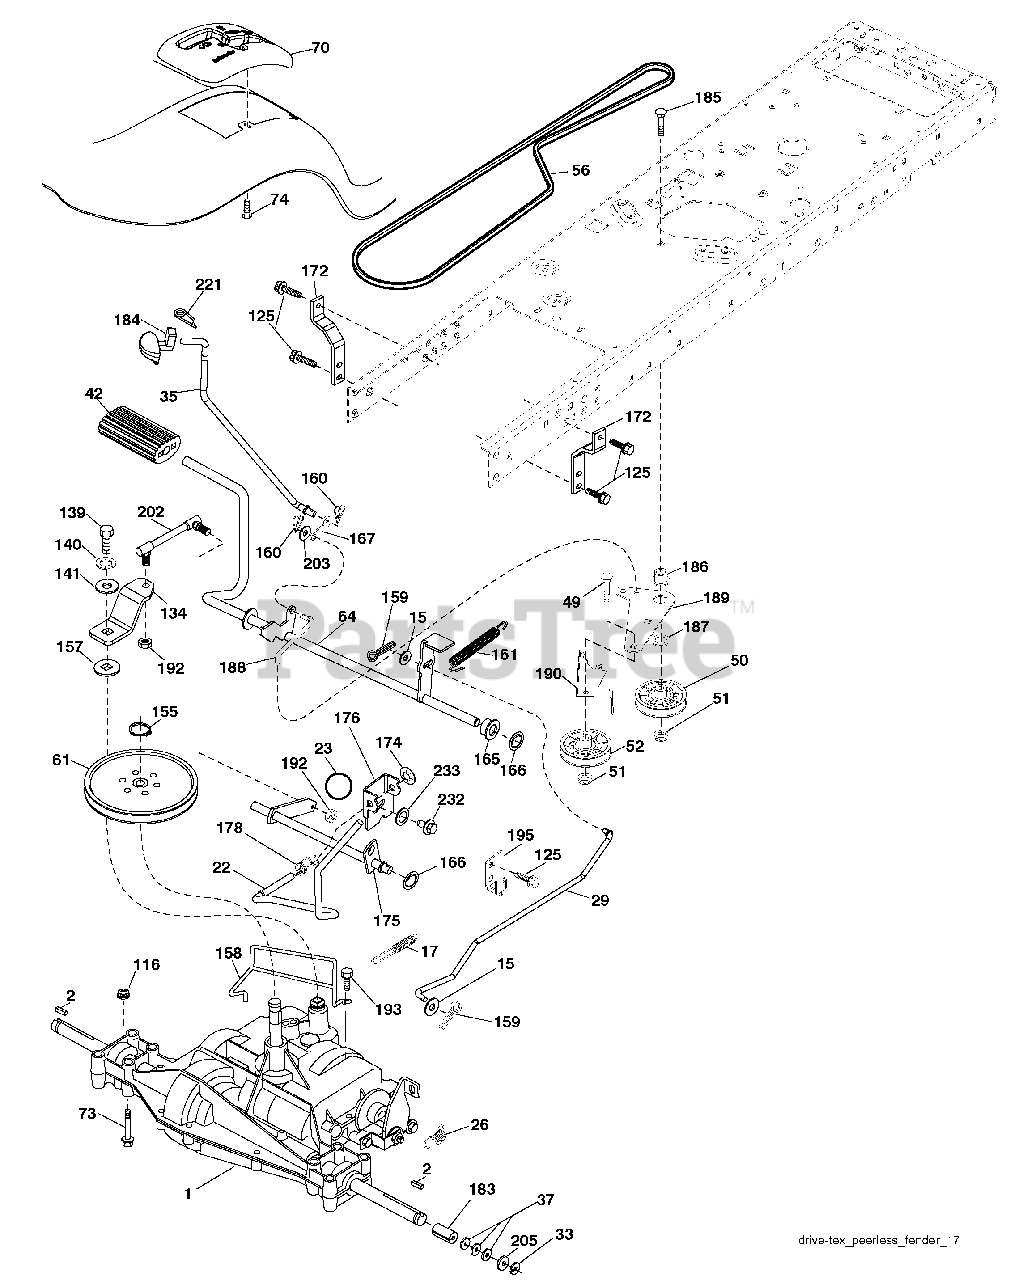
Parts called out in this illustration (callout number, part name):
2	Key Square
15	Washer 13/32 x 13/16 x 16 Ga.
17	Spring, Brake
22	Rod Shift
23	Knob
26	Spring Brake RTN
29	Rod, Brake
33	Ring E
35	Rod, Brake, Park
37	Washer 25/32 x 1-1/4 x 16 Ga.
42	Cover, Foot Pedal
49	Bolt
50	Pulley Idler Flat
51	Lock Nut 3/8-16
52	Idler V-Groove
56	V-Belt, Drive
61	Pulley Transaxle
64	Shaft Asm. Pedal Brake Control
70	Console
73	Bolt 5/16-18 Gr. 5
74	Screw 1/4 x 1/2
116	Nut Lock Hex Flange 5/16-18
125	Screw 5/16-18 x 3/4
134	Arm Shift
139	Bolt 1/4-20 unf Gr. 8 w/Patch
140	Washer Lock Hvy Helical 1/4
141	Washer 9/32 x 3/4 x 10 Ga.
155	Ring Retainer
157	Washer Plate Shf
158	Keeper T/A
159	Pin Cotter 1/8 x 3/4
160	Retainer Clip
161	Spring, Return, Clutch
165	Busing Shaft Brake Hand Control
166	Nut Push .625
167	Latch Brake Parking
172	Strap Torque LH
174	Nut Push
175	Shaft Asm Shift
176	Arm Clevis Rod Shift
178	Spring Shift
183	Spacer, Axle
184	Handle Parking Brake
185	Bolt
186	Spacer Retainer
187	Washer
188	Link Clutch Ground Drive
189	Bellcrank Ground Drive
190	Keeper Bellcrank Ground Drive
192	Nut Lock Center 1/4-28
193	Screw 5/16-18 x 3/4
195	Bracket Brake Rod
202	Link Shift
203	Washer 11/32 x 11/16 x 16 Ga.
205	Washer 25/32 x 1-5/8 x 16 Ga.
221	Retainer Spring Clip Handle
232	Bolt 7/16-14 x 1 Gr. 5
233	Washer Serrated
